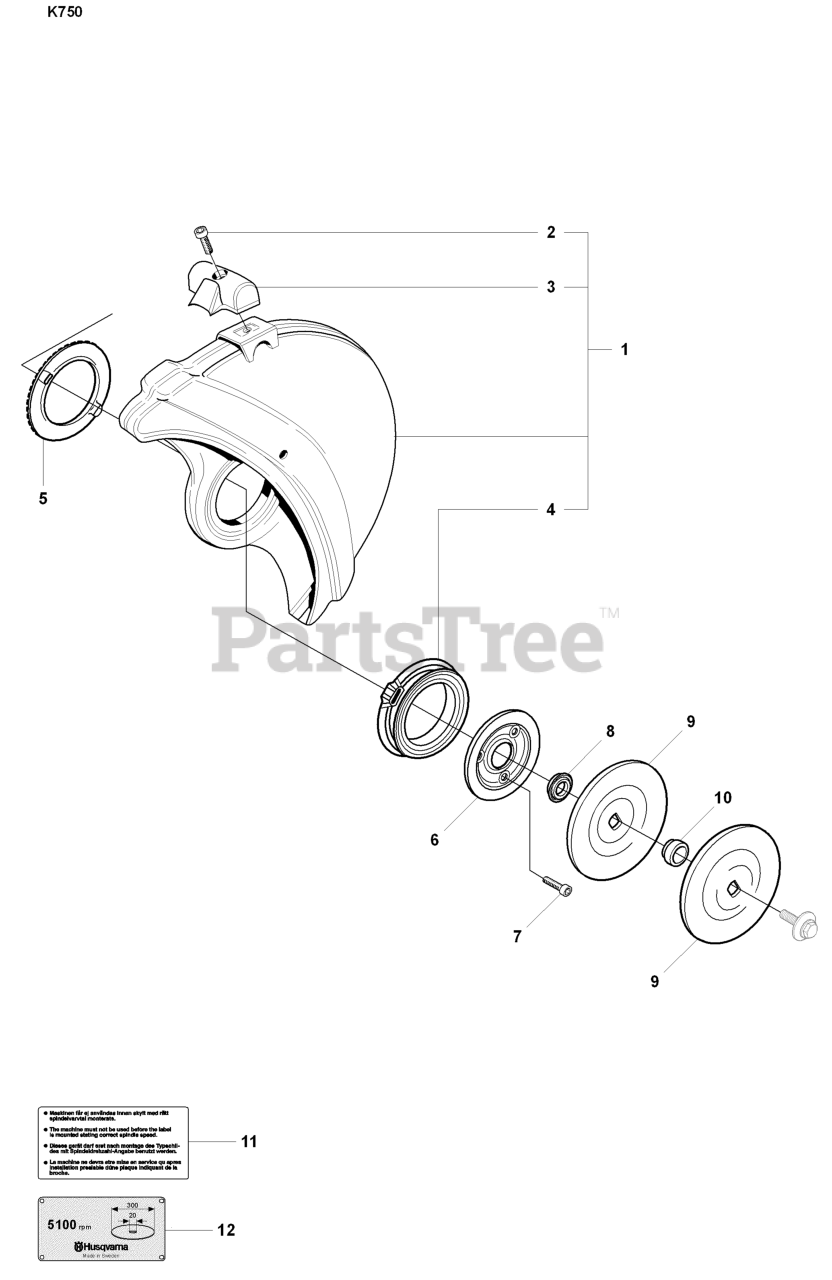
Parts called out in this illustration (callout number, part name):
1	%PROTECTOR
1	PROTECTOR
2	%SCREW
7	SCREW MC6S 5X16
9	WASHER
10	BUSHING
10	BUSHING-30MM
11	INFORMATION LABEL
12	LABEL
12	ARBOR SIZE DECAL/25.4
12	ARBOR SIZE DECAL/20
